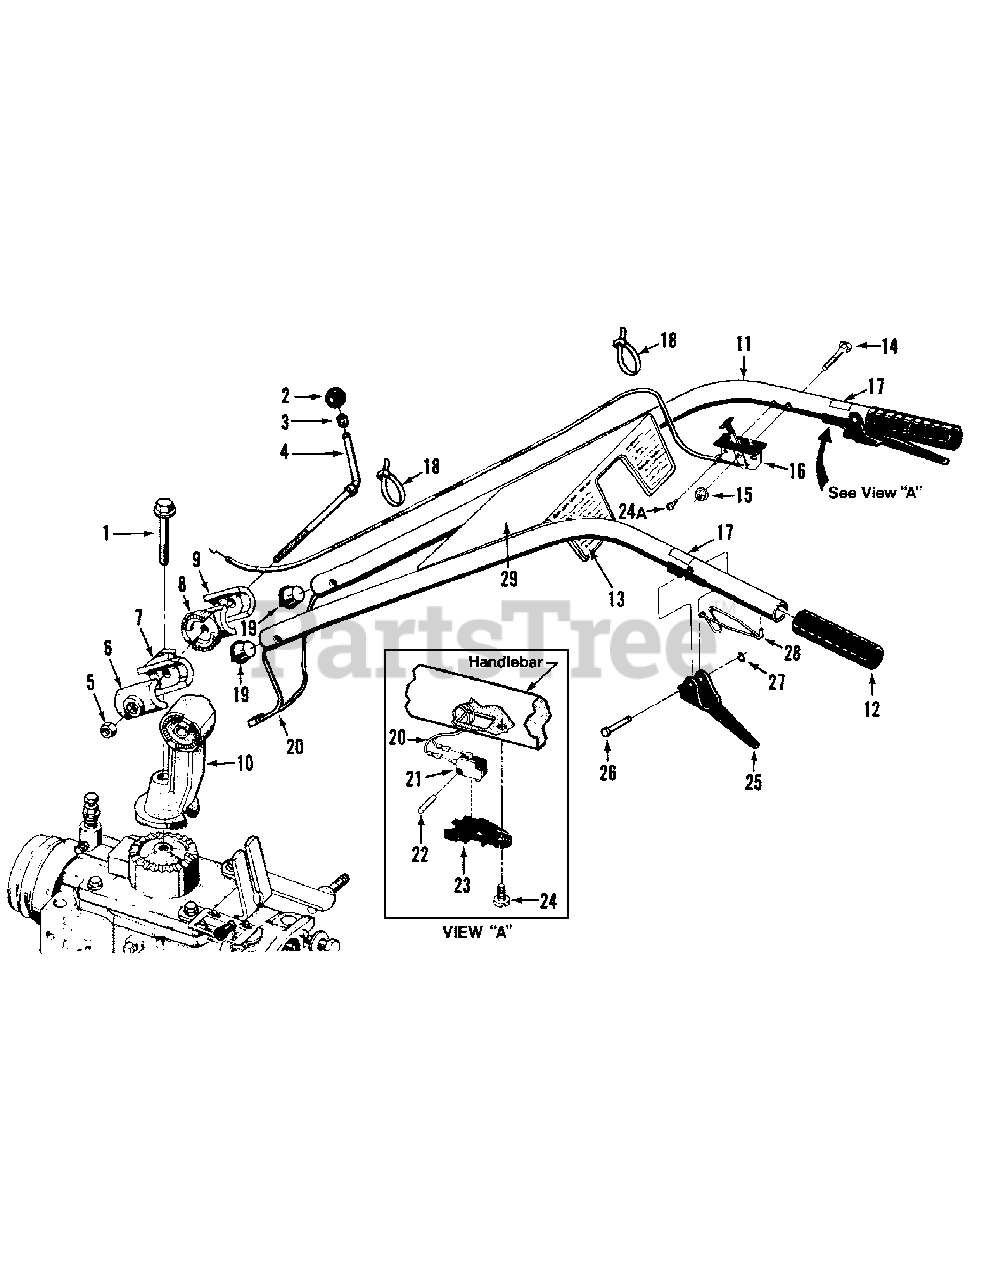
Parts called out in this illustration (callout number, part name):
1	Bolt -Hex hd., flanged self-locking Grade 5, 1/2-13 x 3 -1/2"
2	Knob-handlebar height adjustment
3	Ring-retaining (tolerance ring)
4	Stud-handlebar height adjustment
5	Nut-hex, 1/2"-13
6	Clamp-left, handlebar height adjustment
7	Ratchet-left, handlebar height adjustment
8	Ratchet-right, handlebar height adjustment
9	Clamp-right, handlebar height adjustment
10	Base-handlebar mounting
12	Grip-handlebars
13	Decal-Control panel
14	Bolt-curved hd, GR5, 1/4-20 x 2
15	Nut-hex, flanged self-locking, whiz lock 1/4"-20
16	Throttle Control & Cable, 66"
17	Decal-Forward Interlock Lever
18	Tie-plastic
19	Plug-wire harness retainer
20	Handlebar Wire Harness Assembly forward interlock system
21	Handlebar Switch-forward interlock system
22	Lock Pin-handlebar switch
23	Switch Housing-handlebar switch
23	Switch Assembly (Includes Ref. 21-23)
24	Screw -pan head, #10-16 x 1/2" thread-forming
24A	Screw -pan head, #10-32 x 1/2" thread-forming
26	Pivot Pin -forward interlock lever
27	Retaining Ring -klip ring forward interlock lever
28	Return Spring -fwd interlock lever
29	Label Troy-Bilt Horse
29	Label Troy-Bilt Horse "Big Red"
